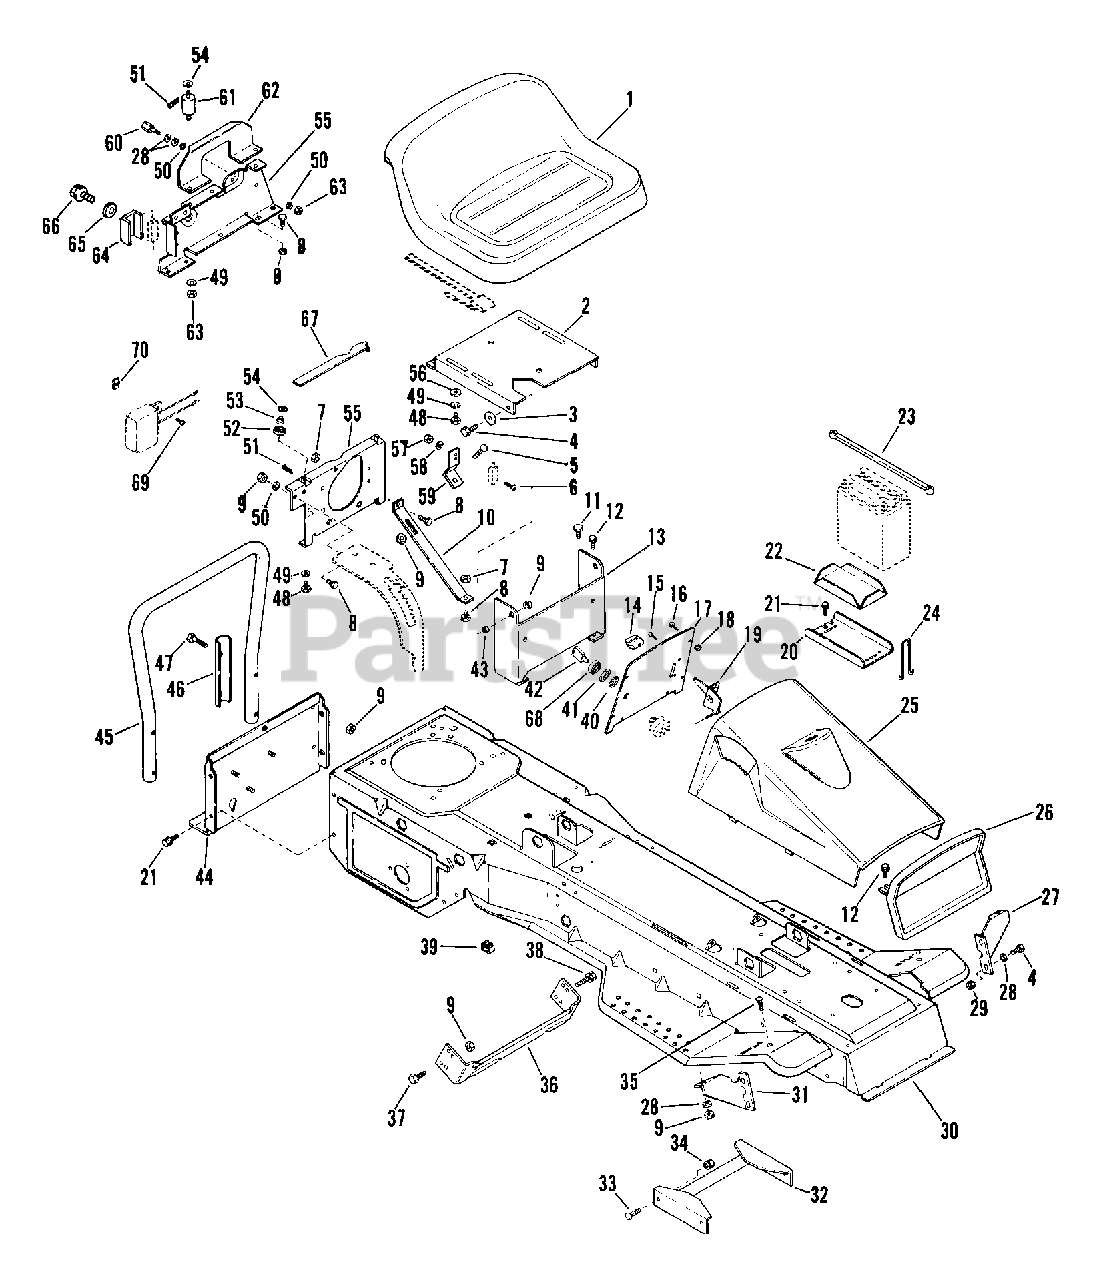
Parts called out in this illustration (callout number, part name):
1	SEAT WITH SWITCH REPLACEMENT P
1	SEAT
2	SEAT BRACKET
3	WSHR-FL-STL .344X1.125X.063PL
4	BLT-HEX .31-18X.75 PL GR2
5	BLT-RDHDSQNK .312-18X.62 PL
6	SCR-MCH 10-24X.62 SLRH PL
7	NUT-LK-CTR .250-20 PL
8	BLT-HEX .25-20X.50 PL GR2
9	NUT-LK .312-18 GR A PL
10	BRACE
11	BLT-HEX .31-18X.50 PL GR2
12	SCR-TAP .250-20X.50 HXSLHDPL
13	SEAT PIVOT BRACKET
15	SCR-TAP 10-24X.375 CRPH 1A
16	SCR-TAP 10-12X.50 CRPH PL A BL
17	DASH PANEL W/SILK SCREEN
17	DASH PANEL-RM
18	PLASTIC GROMMET
19	THROTTLE CONTROL
20	BATTERY TRAY
21	SCR-TAP .312-18X.50 HWH PL TR
22	RUBBER PAD
23	BATTERY STRAP
24	HOOK
26	GRILLE INSERT & SHELL ASSEMBLY
27	L H FENDER BRACE
27	FENDER BRACE
28	WSHR-FL-STL .323X.625X.062 PL
29	NUT-LK-TWIN .312-18 PL
30	FRAME WITH DECALS
31	RH FENDER BRACE
32	FRAME BRACE
33	BLT-RDHDSQNK .312-18X.62SHTPL
34	NUT-FLG. .312-18 PL
35	BLT-RDHDSQNK .31-18X.75 GR5 PL
36	FRAME BRACE
37	BLT-HEX .31-18X.63 PL GR 2
38	SCR-TAP .312-18X1.50 HWH PL TR
39	NUT RETNR .25-20
40	WSHR-LK-INT .625X.045 PL
41	NUT-PANEL .625-32 GRECO
42	KEY SET
43	SPACER BUSHING .5 X .32 X .163
44	BACK COVER
45	TUBE
46	BRACE
47	BLT-HEX .31-18X1.50 PL GR2
48	BLT-HEX .31-18X.75 PL GR5
49	WSHR-LK .312X.097 PL HVY
50	WSHR-LK-INT .313X.030 PL
51	PIN-HAIR INT .08X.18X1.18
52	SPRING CUP
53	SG-COMP .058X.68X.75
54	WSHR-FL-STL.312X.734X.065PL
55	SEAT LEG
56	WSHR-FL-STL .38X.875X.083 PL
57	NUT-HEX 10-24 PL
58	WSHR-LK 10X.047 MED PL
59	SWITCH BRACKET
60	STUD SPACER
61	ISOLATION MOUNT
62	ENGINE CLIP
63	NUT-HEX .312-18
64	CLAMP
65	WSHR-FL-STL .250X.562X.049 PL
66	SCR-TAP 10-16X1.0 SLHP PL AB
67	SEAT HOLD DOWN
68	CAP - IGNITION SWITCH
69	SCR-MCH 10-24X.38 SLTOR PAN PL
70	NUT-KEPS 10-24 PL
